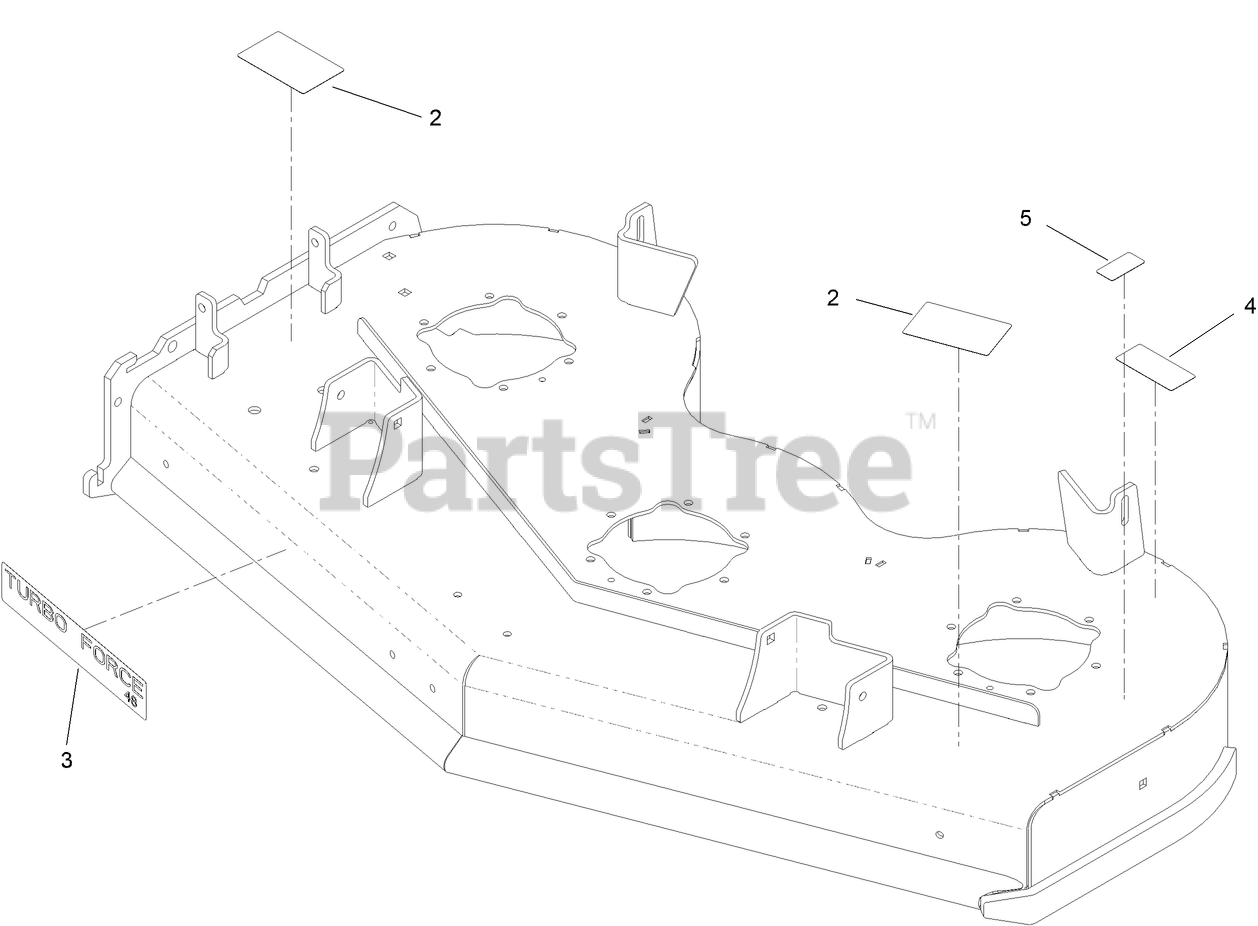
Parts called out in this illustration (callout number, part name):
2	DECAL-DANGER, CE
4	DECAL-DANGER
5	DECAL-NO SPRAY
